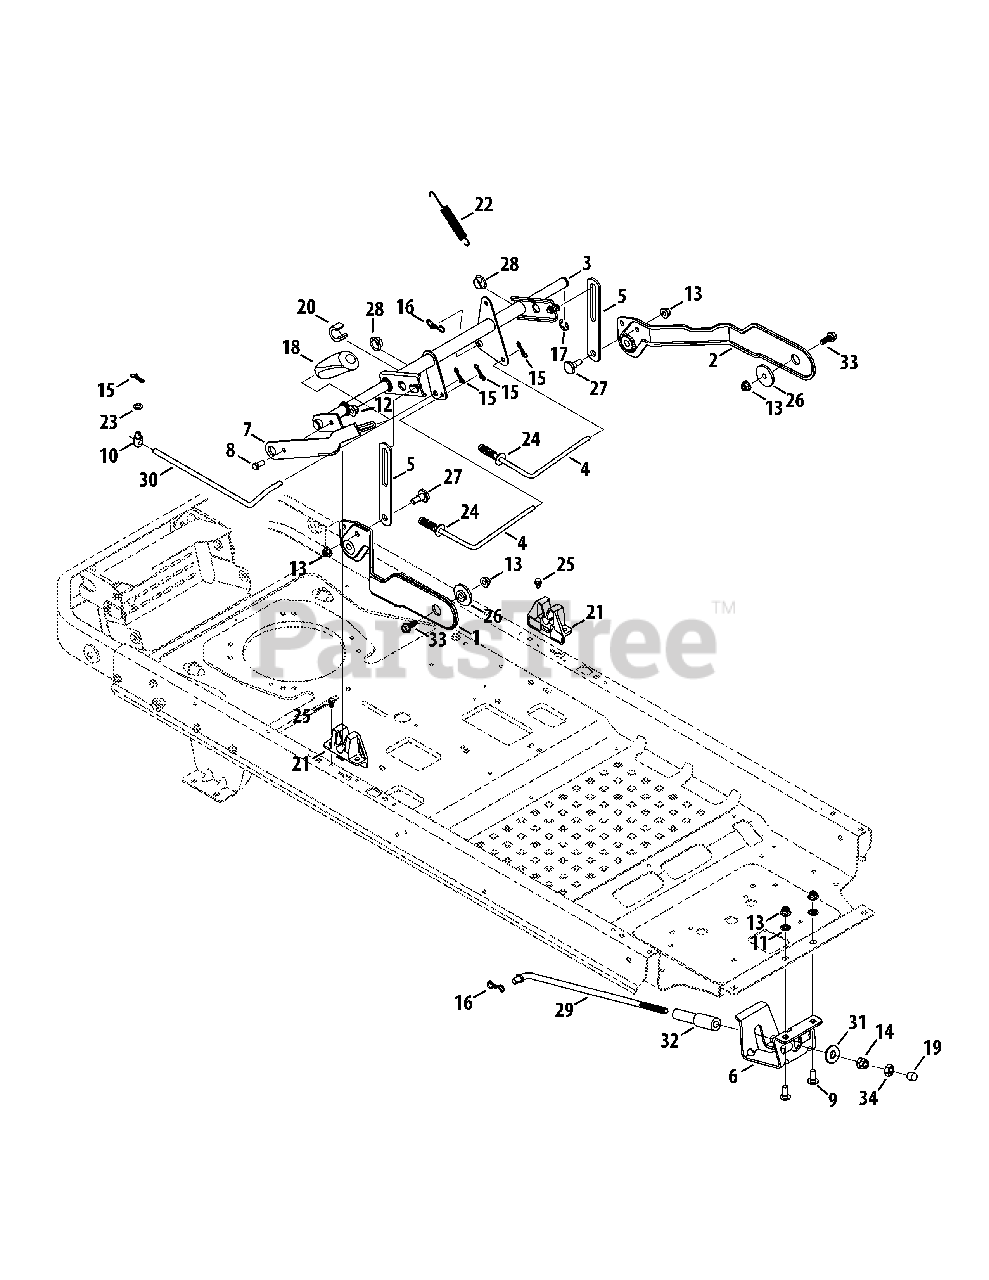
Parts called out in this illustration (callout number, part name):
1	Deck Lift Plate, RH
2	Deck Lift Plate, LH
3	Deck Lift Shift Assembly
4	Brake Rod Assembly
5	Lift Link Plate
6	Rod Support Mounting Bracket
7	Deck Lift Handle
8	Hex Cap Screw, 5/16-18 x .75
9	Carriage Bolt, 3/8-16 x 1.00
10	Ferrule, 3/8-24 x .375
11	Push Nut, 3/8
12	Flange Lock Nut, 5/16-18
13	Flange Lock Nut, 3/8-16
14	Hex Nut, 1/2-13
15	Bow-Tie Cotter Pin
16	Bow-Tie Cotter Pin
17	E-Type Ring, .750
18	Grip, .50 ID
19	End Cap
20	Spacer, .76 ID x .750 LG
21	Deck Lift Bracket
22	Extension Spring, .63 Dia. x 4.95 LG
23	Washer, .375 x .700 x .030
24	Flat Washer, .344 x 1.00 x .063
25	Shoulder Screw, .500 x 1/4-20
26	Shoulder Spacer, .854 x .232
27	Shoulder Screw, .500 Dia. x .434
28	Flange Bearing, .751 x 1.125 x .375
29	Deck Lift Rod
30	Brake Rod
31	Deck Lift pivot Cup
32	Nylon Sleeve, .55 ID x 4.50 LG
33	Screw, 3/8-16 x 1.00
34	Jam Nut, 1/2-13
